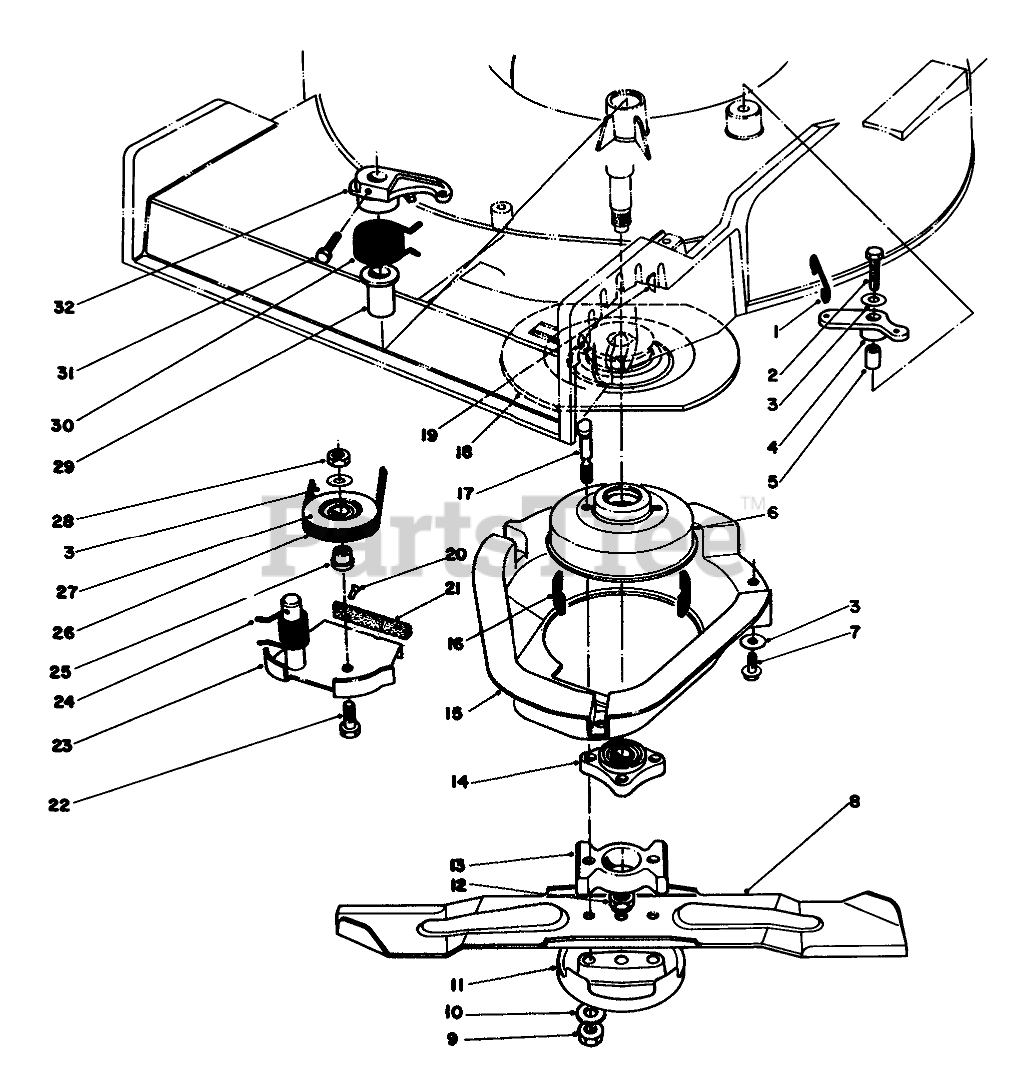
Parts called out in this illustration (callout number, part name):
1	LINK-CONTROL
2	SCREW-HH
3	WASHER-PLAIN
4	BELLCRANK
5	SLEEVE-BELLCRANK
6	Brake Drum
7	SCREW-HWHTF
8	BLADE-21in
9	NUT-LOCK
10	WASHER
11	Anti Scalp Cup
12	NUT-LOCK, NI
13	Spacer Blade
14	HUB ASM
15	SHIELD BBC
16	DAMPENER-VIBRATION
17	BOLT-BLADE
18	Flywheel
19	KEY-WOODRUFF
20	.185 DIA X .375 RT +
21	Paid
22	SCREW-HH
23	Brake Plate (Incl. Ref. #20 & 21)
24	SPRING-TORSION
25	HUB-PULLEY, IDLER
26	V-Belt
27	PULLEY-IDLER
28	NUT-LOCK, NI
29	BUSHING PM
30	SPRING-TORSION
31	SCREW-HH
32	LEVER
